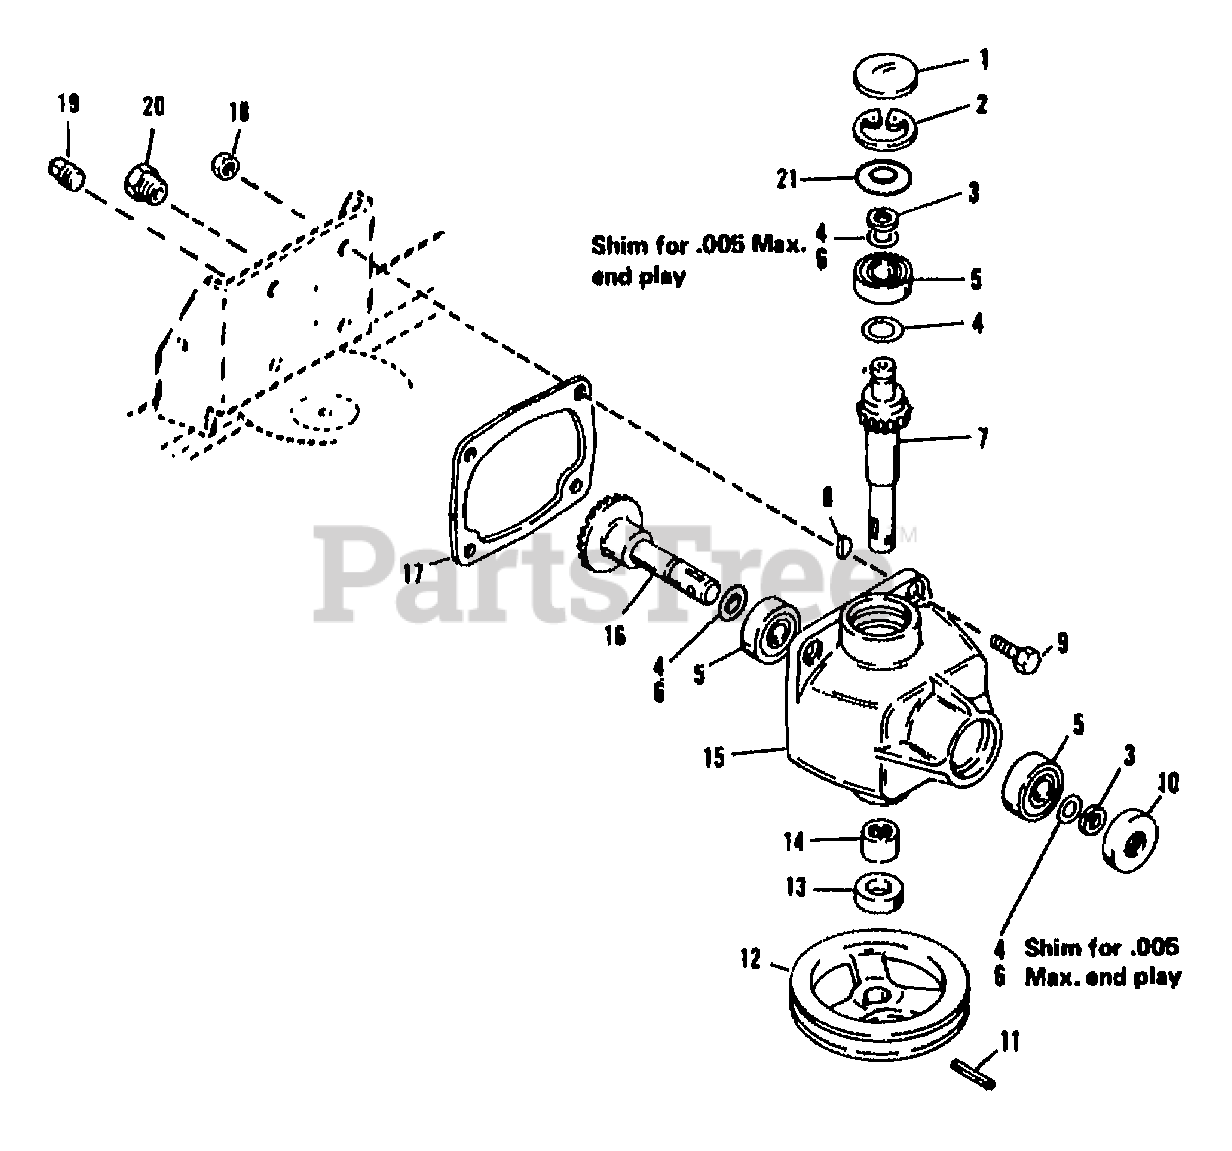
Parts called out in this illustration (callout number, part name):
1	PLUG-EXPANSION
2	RING-RETAIN INT 1.942 DIA
3	RING-RETAINING EXT .694 ID
4	SHIM-1.062X.789X.005
5	BEARING-BALL
6	SHIM-1.062X.789X.01
7	SHAFT-OUTPUT
8	KEY-WOODRUFF .188X.75
9	SCR-HH 5/16-18X1.25 G5ZP
11	SCR-SQ HD SET 5/16X3/4
12	SHEAVE-DRIVE
13	SEAL-OIL
14	BEARING-NEEDLE
15	CASE-GEAR
16	GEAR-BEVEL 26T
17	GASKET
18	NUT-TOP/LK 5/16-18 ZP
19	PLUG-PIPE
20	VALVE
21	SHIM-.005
